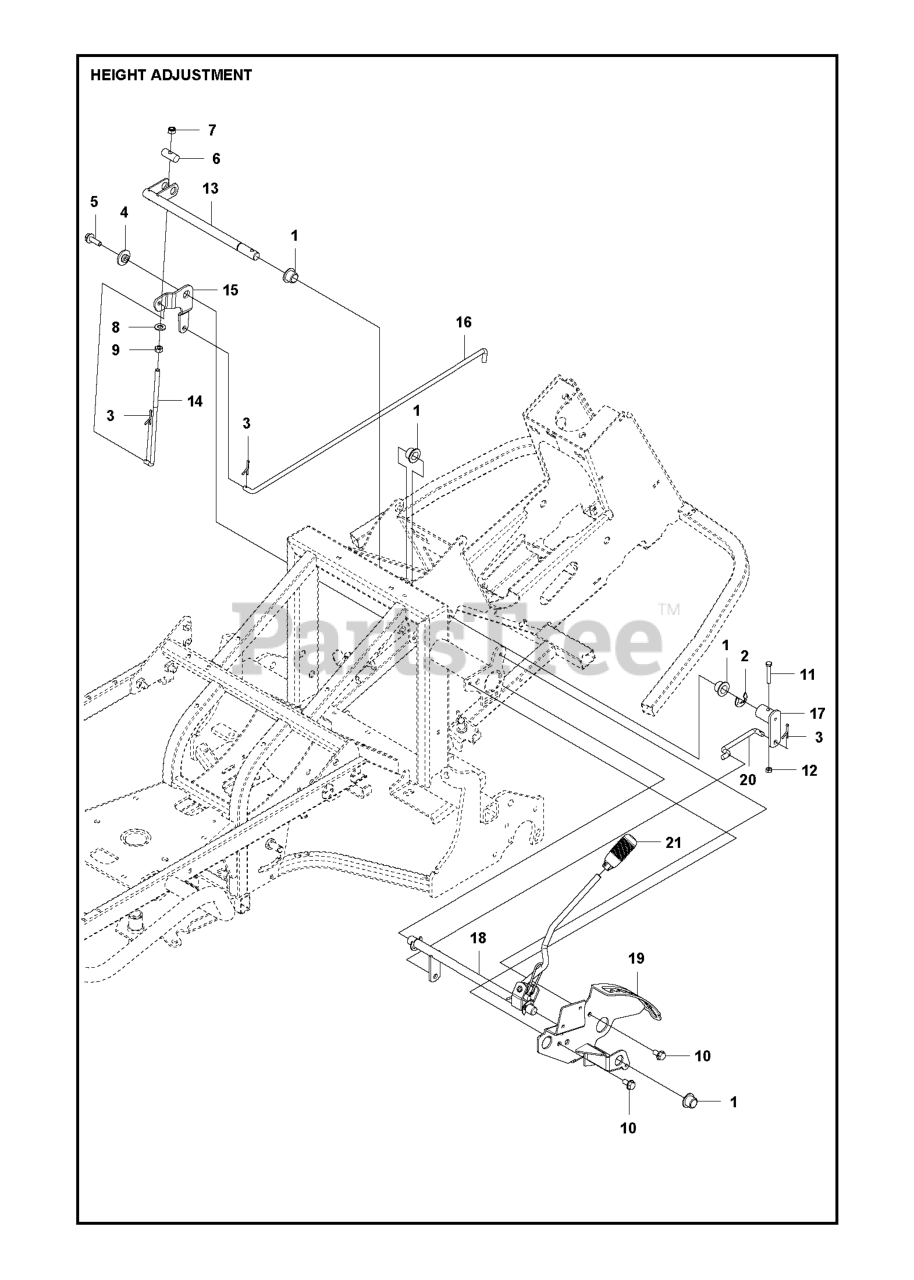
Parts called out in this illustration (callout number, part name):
1	BEARING FLANGE
4	WASHER
5	BOLT
7	LOCKNUT M8
8	WASHER
9	NUT
12	NUT FLANGE - M6
21	GEAR STICK KNOB
